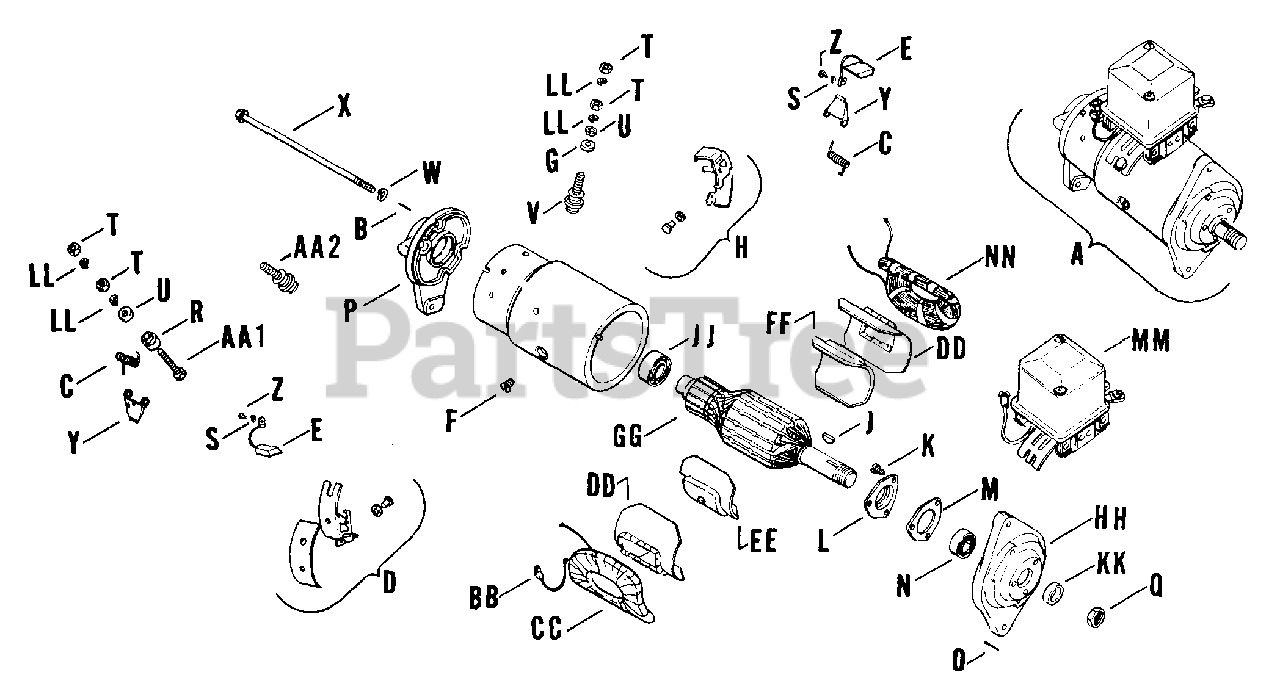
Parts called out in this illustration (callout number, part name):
A	STARTER - DISCONTINUED
C	SPRING - DISCONTINUED
D	HOLDER - DISCONTINUED
E	BRUSH - DISCONTINUED
F	SCREW - DISCONTINUED
G	WASHER - DISCONTINUED
H	HOLDER - DISCONTINUED
J	KEY - DISCONTINUED
K	SCREW - DISCONTINUED
M	GASKET - DISCONTINUED
N	BEARING - DISCONTINUED
O	PIN - DISCONTINUED
P	FRAME - DISCONTINUED
Q	NUT - DISCONTINUED
R	BUSHING - DISCONTINUED
S	WASHER, SPRING LOCK #6
T	NUT - DISCONTINUED
U	Washer, flat - terminal
W	Washer, split - thru bolt
Y	HOLDER - DISCONTINUED
Z	Screw, brush lead
BB	CLIP - DISCONTINUED
CC	COIL - DISCONTINUED
DD	INSULATOR - DISCONTINUED
EE	Shoe, pole plain
GG	ARMATURE - DISCONTINUED
HH	FRAME - DISCONTINUED
LL	WASHER - DISCONTINUED
MM	REGULATOR - USE 275746
